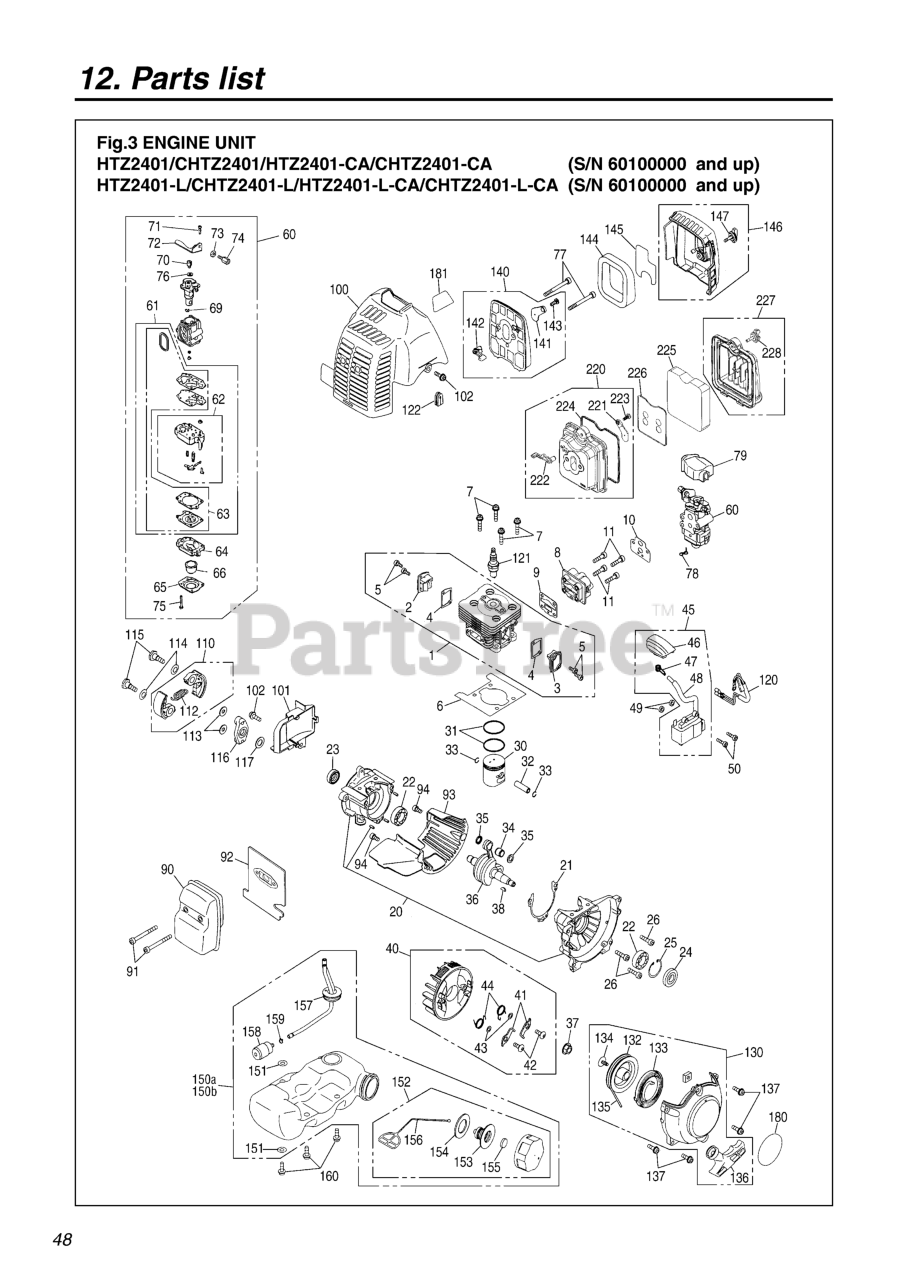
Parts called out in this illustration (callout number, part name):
1	CYLINDER-C
2	COVER, TR-S
3	COVER, TR-F
4	GASKET, TR
5	BOLT, TORX
6	GASKET,BASE
7	BOLT
8	INSULATOR
9	GASKET
10	GASKET, CARB
11	BOLT, TORX
20	CRANKCASE COMP.
21	GASKET, CASE
22	BEARING
23	SEAL
24	SEAL, OIL (RPLS 1140-21220)
25	RING, SNAP, M28 x 1.2
26	BOLT (RPLS 2850-14220)
30	PISTON
31	RING, PISTON
32	PIN, PISTON
33	RING, SNAP (RPLS 1101-41320)
34	BEARING
35	WASHER
36	SHAFT COMP. (RPLS. -4201)
38	KEY
40	ROTOR ASSY
41	PAWL
42	SCREW
43	WASHER
44	SPRING
45	COIL ASSY
46	CAP (RPLS 4810-72110)
47	SPRING
48	TUBE
49	SPACER (RPLS -71260)
50	BOLT TORX
60	CARBURETOR ASSY
61	REBUILD KIT
62	BODY, PUMP
63	KIT, GASKET (REPLACES-06020)
64	BODY, PURGE
65	COVER, PUMP
66	PUMP, PRIMING
69	RING
70	SWIVEL
71	SCREW
73	NUT, CABLE ADJUSTER
74	SCREW, CABLE ADJUSTER
75	SCREW
76	WASHER
77	BOLT
78	CLIP
79	COVER
90	MUFFLER
91	BOLT
92	GASKET, MUFF
93	PLATE
94	BOLT
100	COVER,ENGINE
101	DEFLECTOR
102	BOLT, TORX
110	SHOE-C
112	SPRING
113	WASHER, FLAT (USE 182303)
116	PLATE,CLUTCH
117	WASHER
122	GROMMET
130	RECOIL-A
132	REEL
133	SPRING, SPIRAL
134	SCREW (RPLS -75150)
135	ROPE
136	KNOB (RPLS -75420)
137	BOLT, TORX
140	BODY-A
141	PLATE, CHOKE
143	SCREW (REPLACES 50030272)
144	ELEMENT
145	SCREEN
146	COVER ASSEMBLY
147	KNOB (RPLS -82220)
150A	TANK ASSY
151	PACKING
152	CAP ASSY (RPLS -85201)
153	HOLDER (REPLACES -85230)
154	PACKING
155	FILTER
156	STOPPER
157	PIPE-C
158	FILTER ASSY
159	CLIP (REPLACES 2841-31280)
160	BOLT, TORX
180	LABEL, RECOIL
181	LABEL, COVER
220	BODY ASSY
221	PLATE, CHOKE
222	LEVER
223	SCREW
224	PACKING
225	ELEMENT
227	COVER A (RPLS. T1513-82200)
228	KNOB
